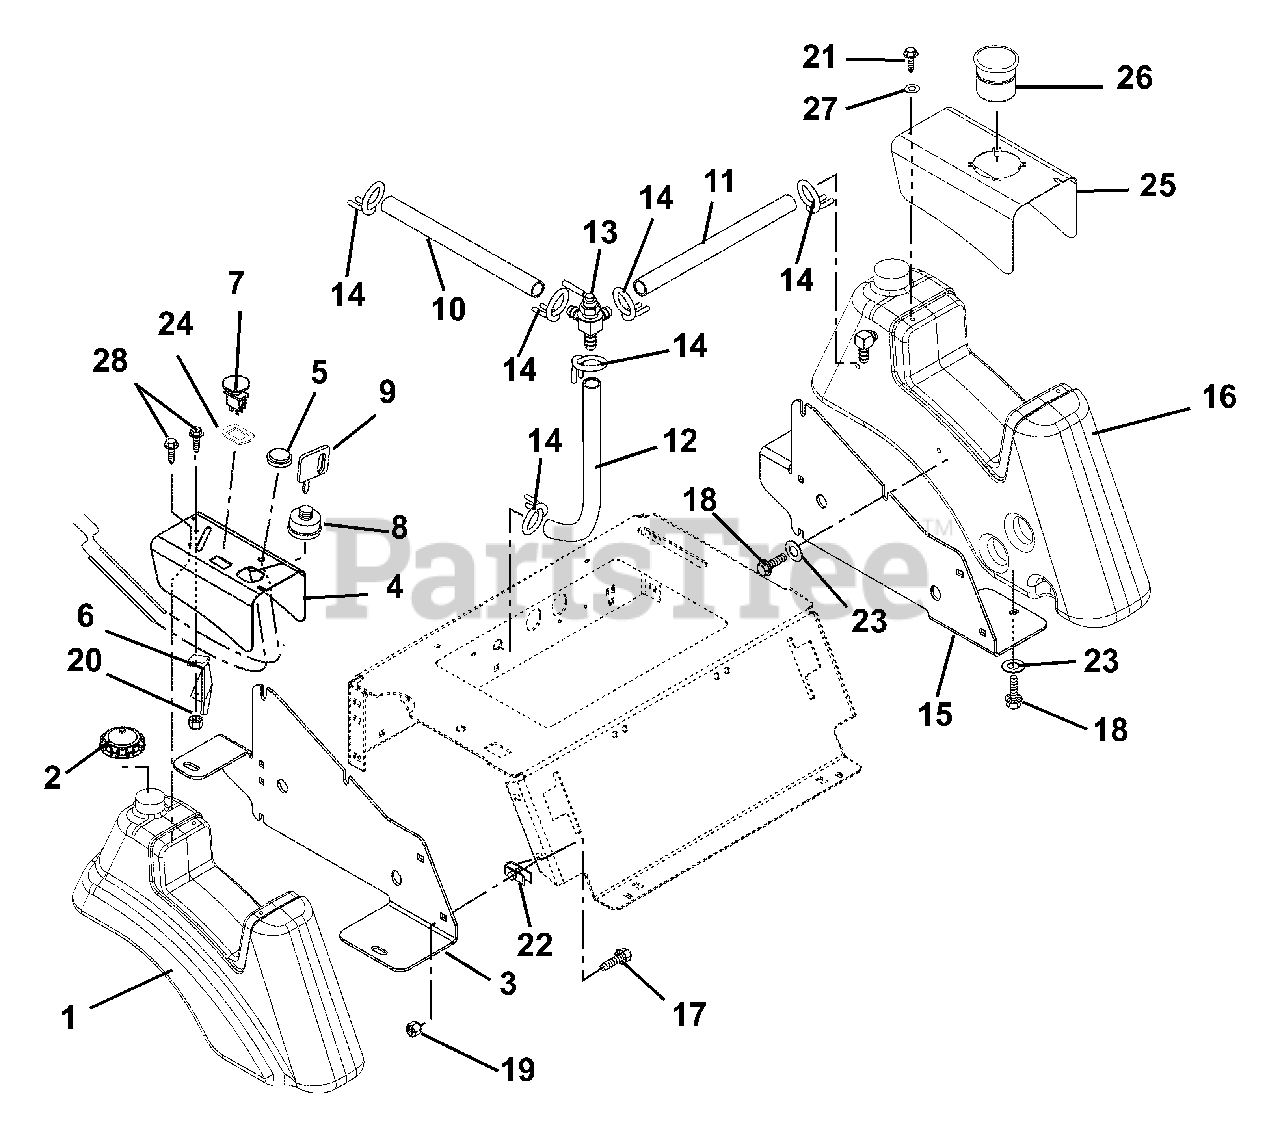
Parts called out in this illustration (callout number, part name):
1	Tank, Fuel - Right Hand
2	Fuel Cap
3	Seat Plate/Tank Support Right Hand
4	Right Hand Console
5	Hole Plug, Plastic .44 Hole
6	Throttle Cable
7	Switch, Clutch
8	Key Switch
9	Key with Cap
10	Gas Line, Bulk .25 I.D. x 38 Long
11	Gas Line, Bulk .25 I.D. x 27 Long
12	Gas Line, Bulk .25 I.D. x 14 Long
13	Valve, Fuel
14	Clamp, Hose Wire .490/.510 x .092
15	Seat Plate Left Hand
16	Tank, Fuel - Left Hand
17	Bolt, Round Head Square Neck .38-16 x 1.00 Grade 5
18	Bolt, Serrated Hex Flange Washer Head .312-18 x .50
19	Nut .38-16 Flange Nyloc
20	Nut-Locking-Nylon 10-24 with Insert
21	Screw, Machine 10-24 x 3/8 Slotted Hex
22	Retainer .38 Push-On
23	Washer-Flat-Steel .347 x 1.254 x .048
24	Shim, PTO Switch
25	Left Hand Console
26	Cupholder
27	Washer, Fender 3/16 x 3/4
28	Screw-Machine 10-24 x .50 Hex Washer Head
